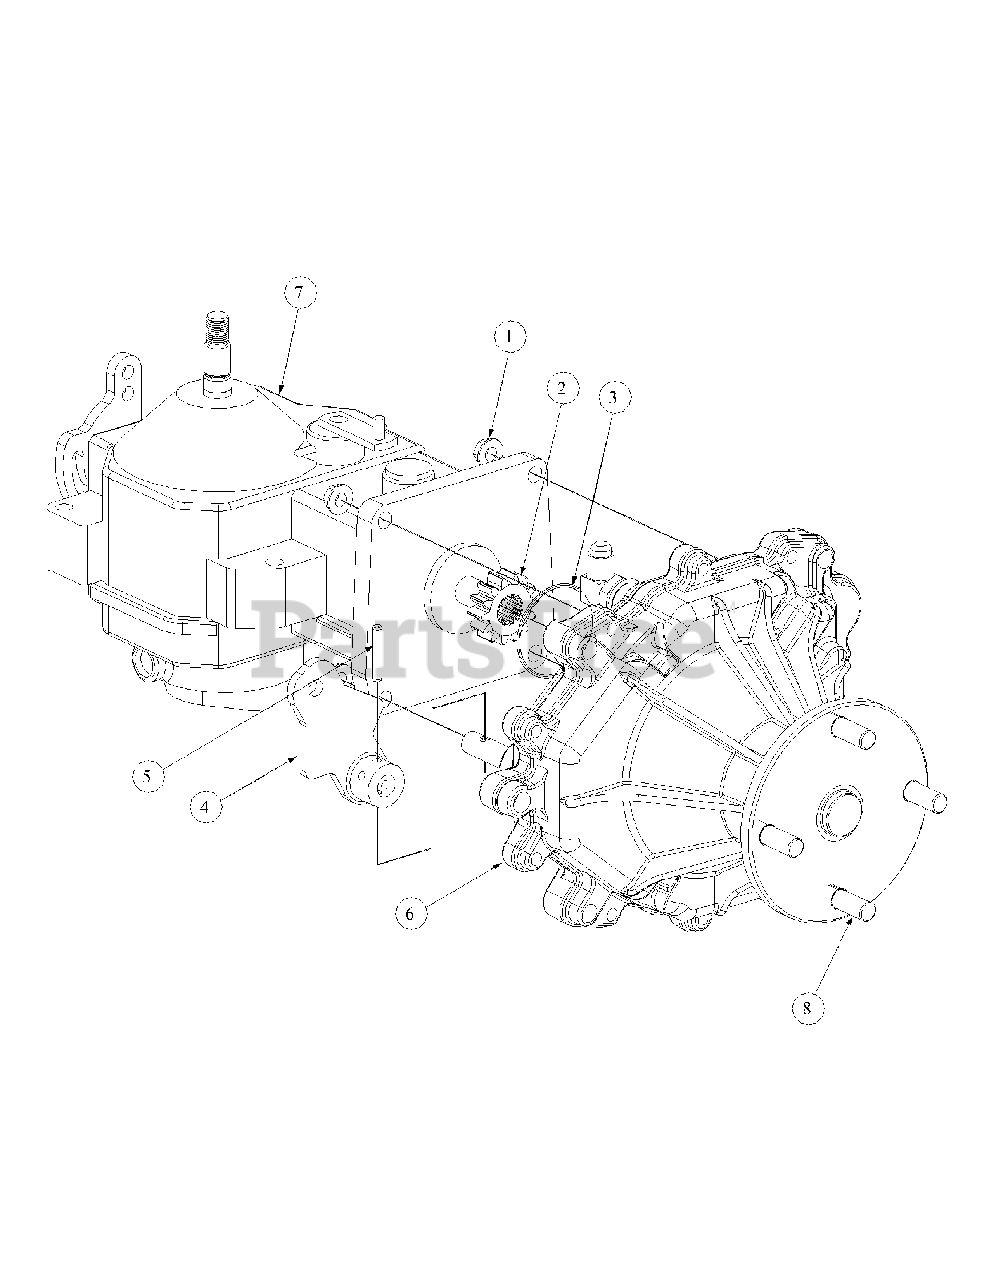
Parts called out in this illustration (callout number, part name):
1	Hex Flange, Lock Nut, 5/16-18
2	Gear, Spur, 14T
3	O-Ring, 2.00 x .070
4	Lever, Bracket, Park
5	Pin, Spirol, 3/16 x 1.25 HD
6	Transmission Assembly
8	Rib Neck Stud, 1/2-20
